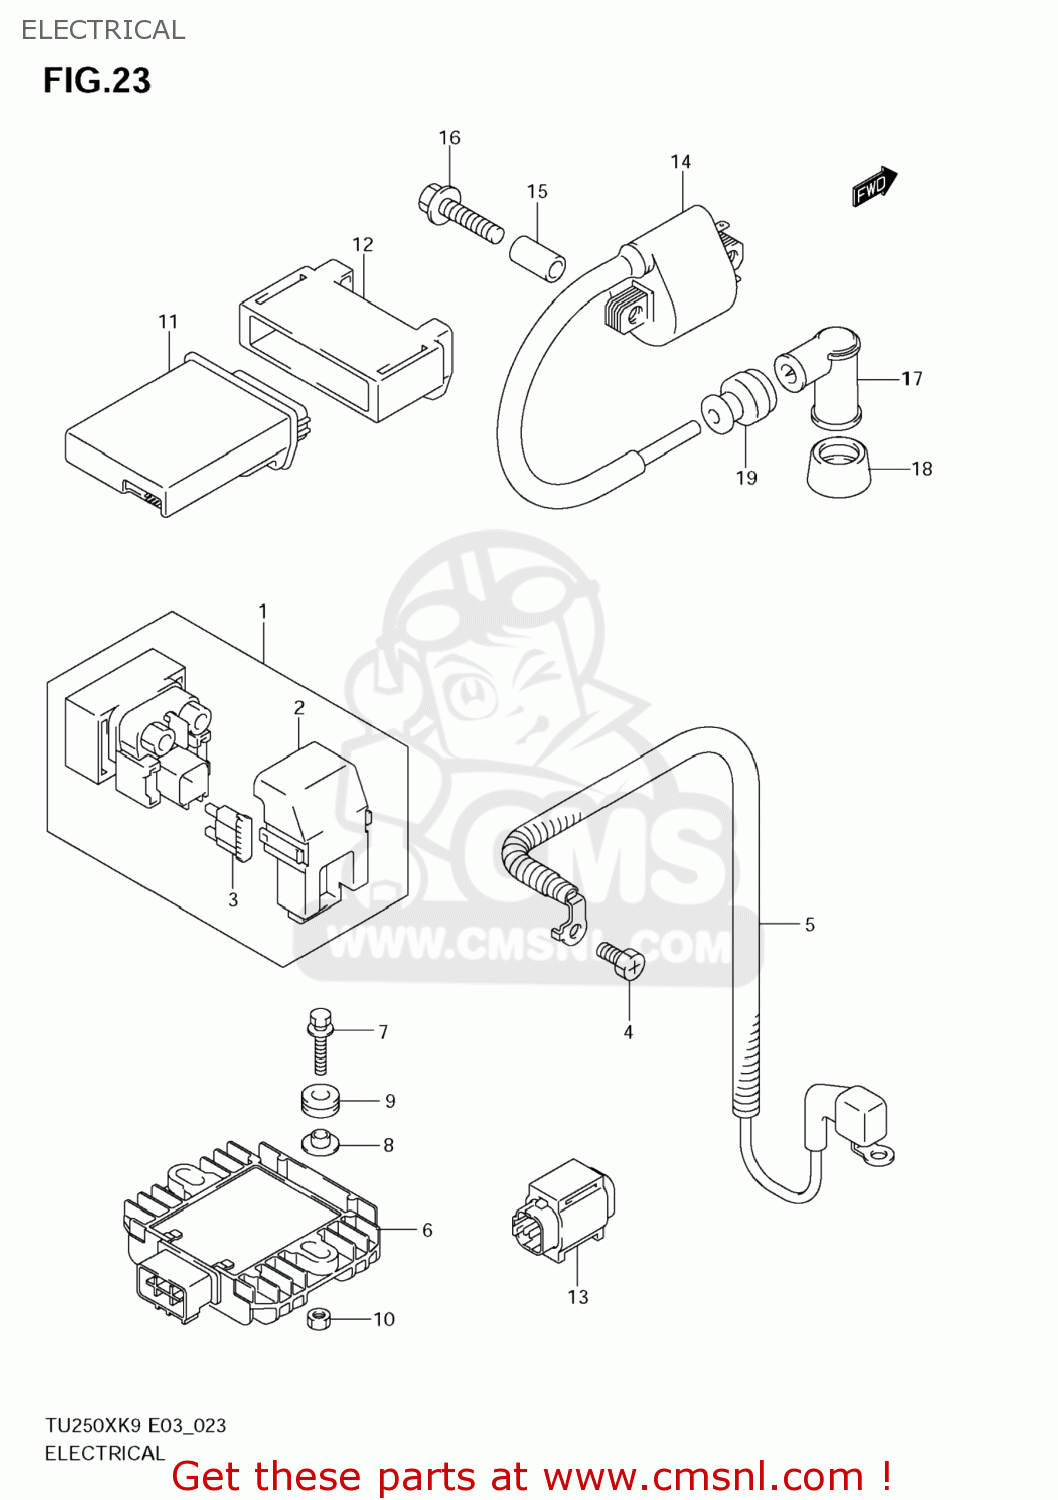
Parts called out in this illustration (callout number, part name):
1	RELAY ASSY,STARTING MOTOR
2	COVER
3	FUSE(30A)
4	SCREW(6X8)
5	WIRE,STARTER MOTOR LEAD
6	RECTIFIER ASSY
7	BOLT(6X30)
8	SPACER(6.2X8.4X6.9)
9	CUSHION
10	NUT
11	CONTROL UNIT FI
12	CUSHION,FI CONTROL UNIT
13	SENSOR ASSY,FUEL CUT
14	COIL ASSY,IGNITION
15	SPACER(6.2X12X14)
16	BOLT
17	CAP ASSY,SPARK PLUG
18	SEAL,SPARK PLUG
19	SEAL,HIGH TENSION CORD
